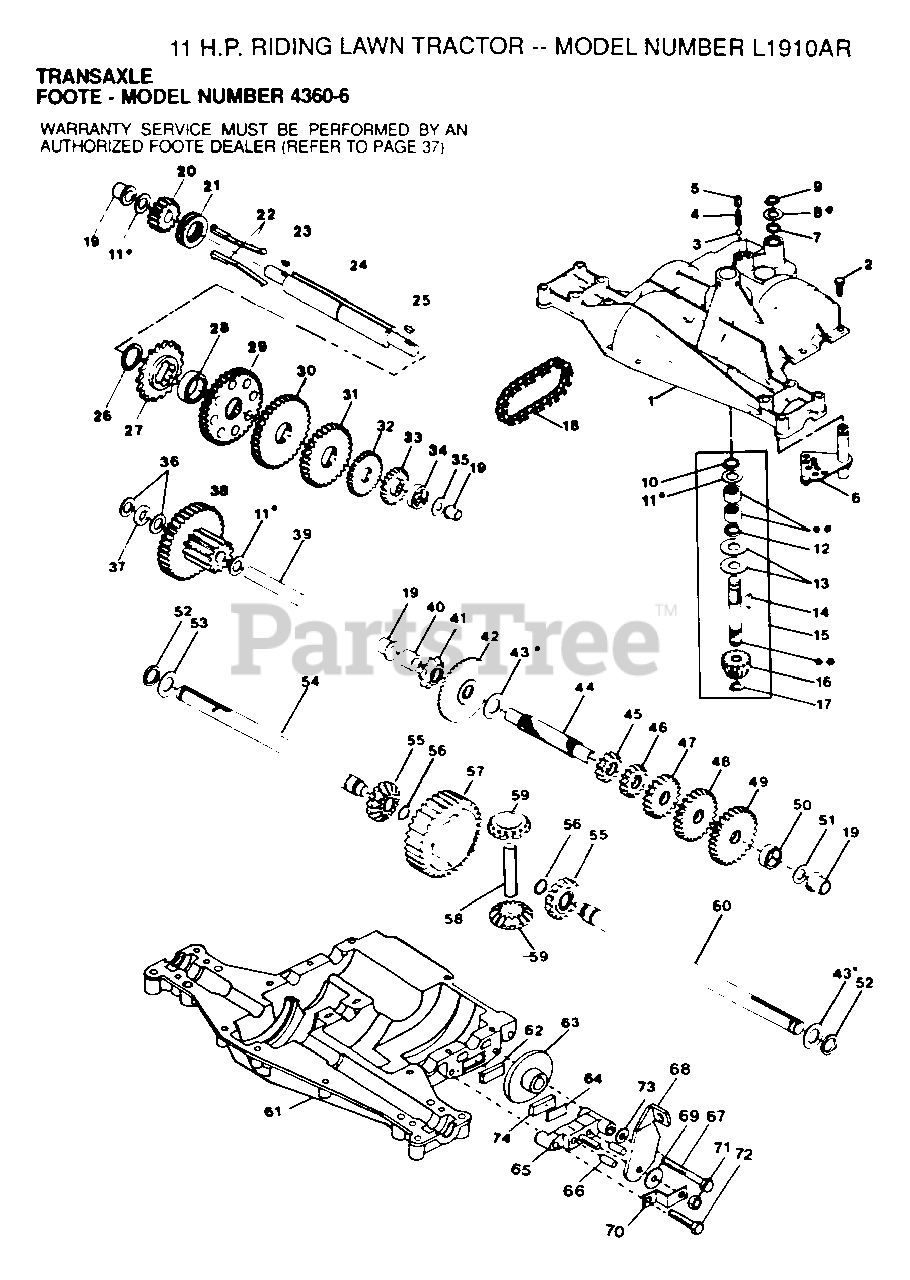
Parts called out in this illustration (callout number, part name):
1	HOUSING UPPER
3	BALL DETENT
4	SPRING, DETENT
5	SCREW, SET
6	ASSY SHIFTER
8	WASHER PLAIN
8A	WASHER PLAIN
8B	WASHER PLAIN
8C	WASHER PLAIN
8D	WASHER PLAIN
8E	WASHER PLAIN
8F	WASHER PLAIN
9	RING RETAINING
10	RING RETAINING
11	WASHER PLAIN
11A	WASHER PLAIN
11B	WASHER, PLAIN .632 X 1.00 X .026
11C	WASHER PLAIN
11D	WASHER PLAIN
11E	WASHER PLAIN
11F	WASHER PLAIN
11G	WASHER PLAIN
11H	WASHER, PLAIN .632 X 1.00 X .060
11I	WASHER PLAIN
13	WASHER, PLAIN .632 X 1.38 X .046
14	KEY WOODRUFF #9
15	ASSY KIT INPUT SHAFT
16	PINION, BEVEL, 14 TEETH
17	RING, RETAINING
18	CHAIN, 24 PITCHES
19	BEARING, FLANGE
20	GEAR SPUR, 14 TEETH
21	COLLAR CLUTCH
22	KEY CLUTCH
23	KEY WOODRUFF #3
24	SHAFT INTERMEDIATE
25	KEY, WOODRUFF, #61
26	RING, RETAINING
27	SPROCKET, 18 TEETH
29	GEAR, SPUR, 37 TEETH
30	GEAR, SPUR, 30 TEETH
31	GEAR, SPUR, 25 TEETH
32	GEAR, SPUR, 22 TEETH
35	WASHER, PLAIN .640 X 1.37 X .061
36	WASHER, PLAIN .632 X 1.00 X .026
37	SPACER .630 X 1.00 X .169
38	ASSY GEAR COMB 12&35 TEETH
39	SHAFT IDLER
40	SPACER .635 X .875 X .755
41	SPROCKET, 9 TEETH
42	GEAR, BEVEL, 42 TEETH
43	WASHER PLAIN
43A	WASHER PLAIN
43B	WASHER PLAIN
43C	WASHER PLAIN
43D	WASHER PLAIN
43E	WASHER PLAIN
43F	WASHER, PLAIN .758 X 1.25 X .031
43G	WASHER PLAIN
43H	WASHER PLAIN
43I	WASHER PLAIN
43J	WASHER PLAIN
43K	WASHER PLAIN
43L	WASHER PLAIN
44	SHAFT, DRIVE
45	GEAR, SPUR, 12 TEETH
46	GEAR, SPUR, 20 TEETH
47	GEAR, SPUR, 25 TEETH
48	GEAR, SPUR, 28 TEETH
49	GEAR, SPUR, 31 TEETH
51	WASHER, PLAIN .632 X 1.00 X .060
53	WASHER PLAIN
54	AXLE LEFT HAND
55	GEAR, MITER, 15 TEETH
56	RING, RETAINING
57	GEAR, SPUR, 32 TEETH
58	SHAFT, CROSS
59	GEAR, MITER, 15 TEETH
60	AXLE, R.H.
61	HOUSING LOWER
62	PUCK, FRICTION
63	DISC, BRAKE
65	JAW, BRAKE
66	PIN, DOWEL
67	SCREW TAPPING
68	LEVER, ACTUATING
69	WASHER, PLAIN .321 X 1.00 X .055
70	BRACKET, ANTI-ROTATION
71	LOCKNUT 5/16-24
72	SCREW TAPPING
73	WASHER PLAIN
74	PUCK, FRICTION
